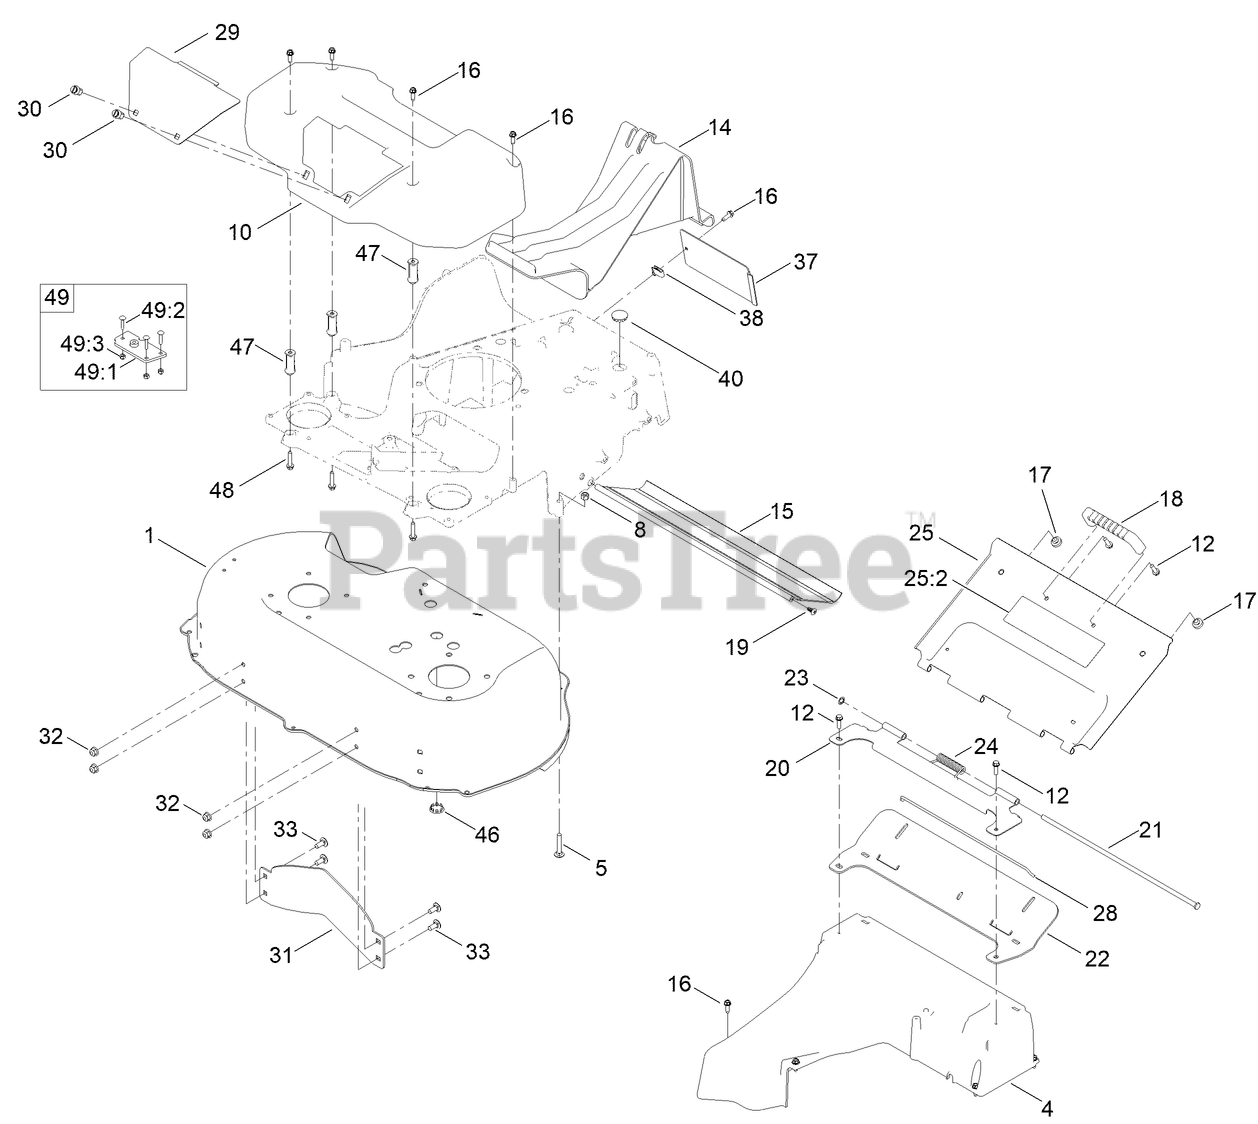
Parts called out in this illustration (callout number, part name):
1	TURFMASTER 30 DECK ASM [RED]
5	BOLT-CAR
8	NUT-LOCK, NI
10	COVER-BELT
12	SCREW-HWH
14	PLUG-MULCH
15	SHIELD-TRAILING
16	SCREW-HWHTF
17	BUMPER
18	HANDLE-DOOR
19	SCREW-PTH
20	BRACKET-HINGE
21	PIN-HINGE
22	SEAL-DOOR
23	RING-RETAINING
24	SPRING-TORSION, COVER
25	REAR DOOR ASM
25:2	DECAL-WARNING
28	CLIP-SEAL
29	PANEL-ACCESS
30	FASTENER
31	BAFFLE-CONTROL
32	NUT-HF, NI
33	SCREW-CARR
37	COVER-FRAME
40	PLUG-BUTTON
46	PLUG-BUTTON
47	SPACER-FRAME, 30 IN.
48	SCREW-HWHTF
49	FRAME-PLATE KIT
49:1	PLATE-FRAME, ASM
49:2	SCREW-CARR
49:3	NUT-LOCK, NI
